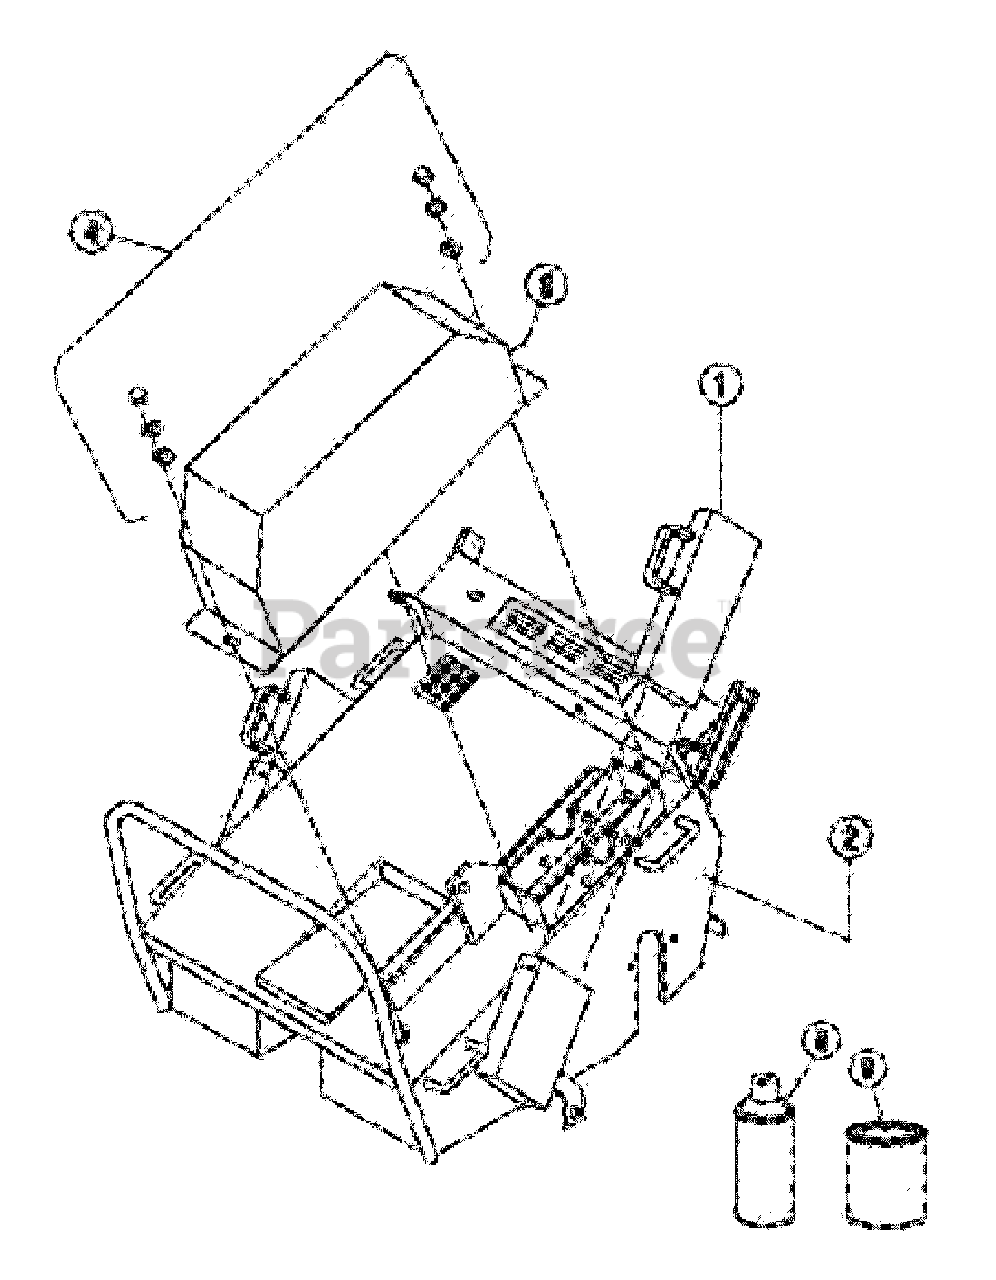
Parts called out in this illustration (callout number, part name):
1	Weight, 36 lbs., solid steel
2	Housing with decals
3	Drive guard with decals
4	Drive guard fastener kit
5	Paint, orange, 12.5 oz. can
6	Paint, orange, 1qt. can
7	Decal kit, AR19
